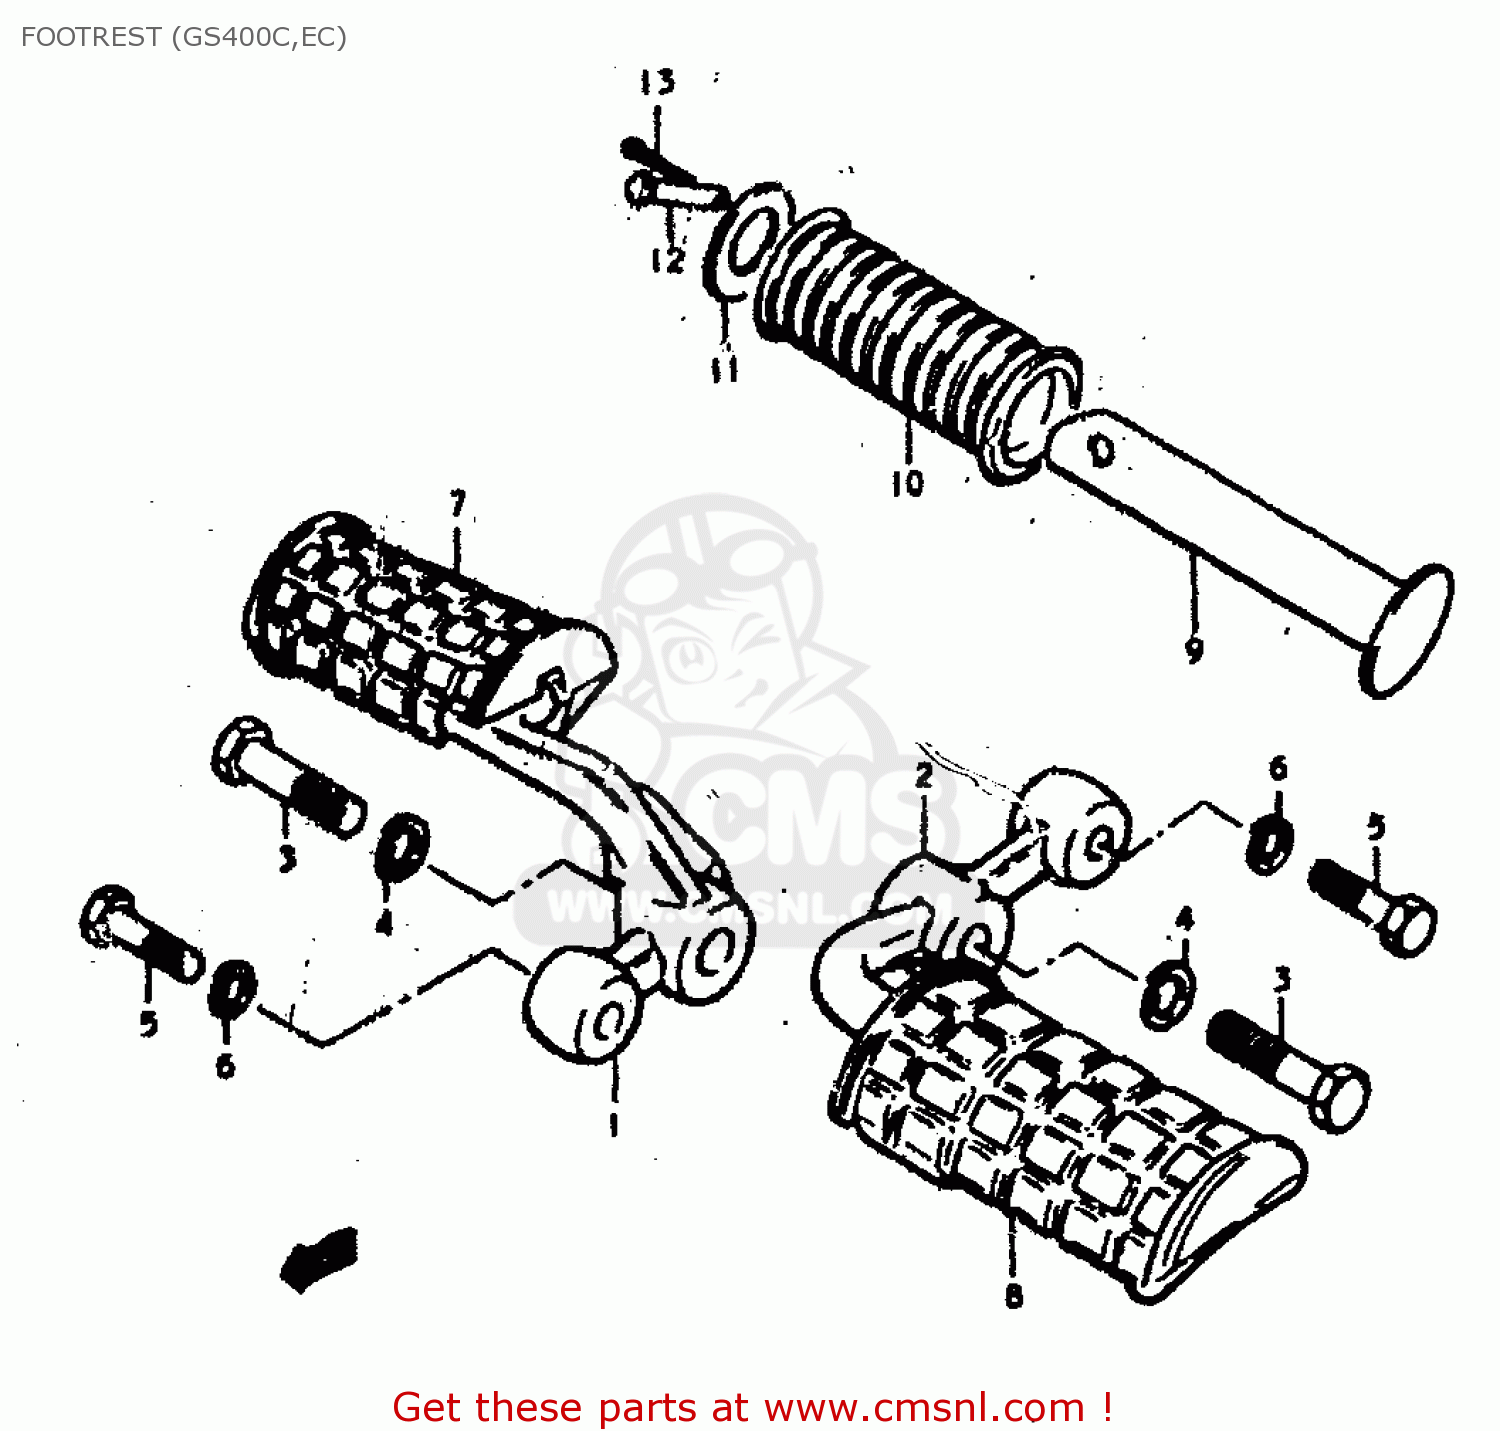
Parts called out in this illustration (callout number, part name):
1	BAR,FRONT FOOTREST
2	BAR,FRONT FOOTREST,LEFT
3	BOLT
4	LOCK WASHER
5	BOLT 8X40
6	LOCK WASHER
7	RUBBER,FR FOOTREST,R
8	RUBBER,FOOTREST
9	BAR,FOOTREST RUBBER
10	RUBBER,PILLION FOOTREST
11	WASHER (19.5X32X2)
12	PIN
13	PIN 20X20
